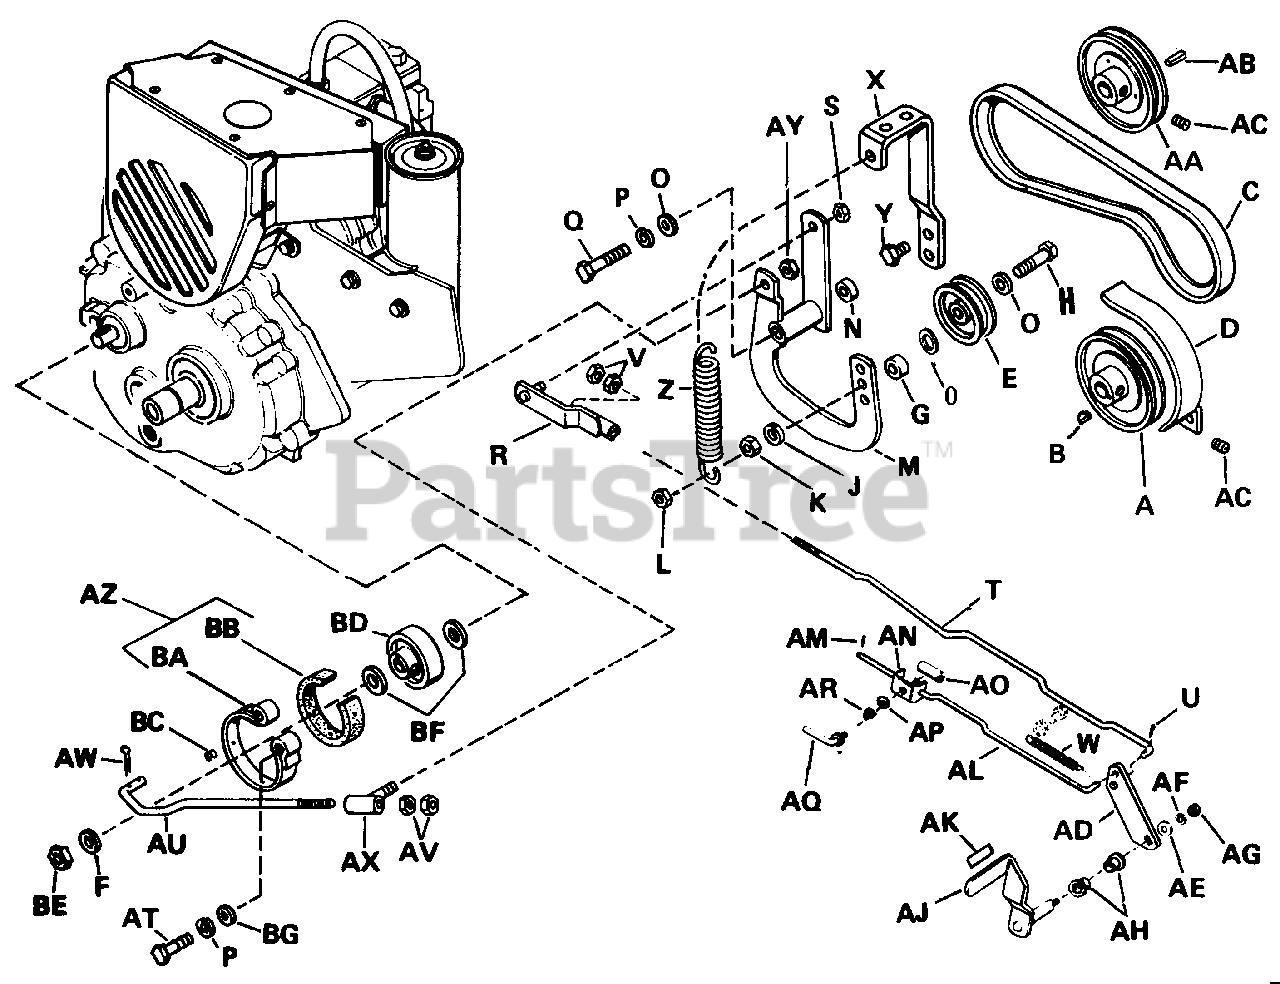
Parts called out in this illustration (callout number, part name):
A	Driver Pulley
B	Woodruff Key, 3/16" x 3/4"
C	BELT, A-Sect, 47.30
D	Belt Guard Assembly
E	Idler Pulley
F	Plain Washer, 3/8"
H	Hex. Capscrew, 3/8-16 x 2-1/4" lg.
J	Lock Washer, 3/8"
K	Full Hex. Nut, 3/8"-16 N.C.
L	Jam Hex. Lock Nut. 3/8"-16 N.C.
M	Idler Lever Assembly
O	Plain Washer, 3/8"
P	Lock Washer, 3/8"
Q	Hex. Capscrew, 7/16"-14 x 3-3/4"
R	Rod Guide Assembly,
S	Full Hex. Lock Nut, 5/16"-18 N.C.
T	Clutch & Brake Rod
U	Cotter Pin, 1/8" x 3/4" lg.
V	Full Hex. Nut, 5/16"-18 N.C.
W	Front Tension Spring
X	SpringBracket, 1/4x 1 x 11-1/4"
Y	Hex. Hd. Capscrew, 3/8 x 3/4"
Z	Idler Pulley Spring
AA	Driven Pulley
AC	Cup Pt. Socket Hd. Set Screw, 5/16-18 x 5/16"
AD	Food Pedal Arm, 1/4 x 1-3/4 x 5-7/8"
AE	Plain Washer, 3/8"
AF	Lock Washer, 3/8"
AG	Full Hex. Nut, 3/8" 16 N.C.
AJ	Foot Pedal Assembly
AK	Pedal Pad
AL	Parking Brake Rod
AM	Cotter Pin, 3/32" x 3/4" lg.
AN	Parking Brake Bracket Assy.
AP	Plain Washer, 7/16"
AQ	Parking Brake Lock
AR	Conical Spring
AT	Hex. Capscrew, 3/8" 16 x 1-3/4" lg.
AU	Brake Rod
AV	Full Hex. Nut, 3/8"-16 N.C.
AW	Cotter Pin, 3/32" x 3/4" lg.
AX	Rod Guide Assembly
AY	Full Hex. Lock Nut, 5/16"-18 N.C.
AZ	Brake Band & Lining Assembly
BA	Brake Band
BB	Brake Lining
BC	Rivet No. 7 x 1/4" lg.
BE	Lock Nut. 7/16"-14
BG	Plain Washer 5/16"
